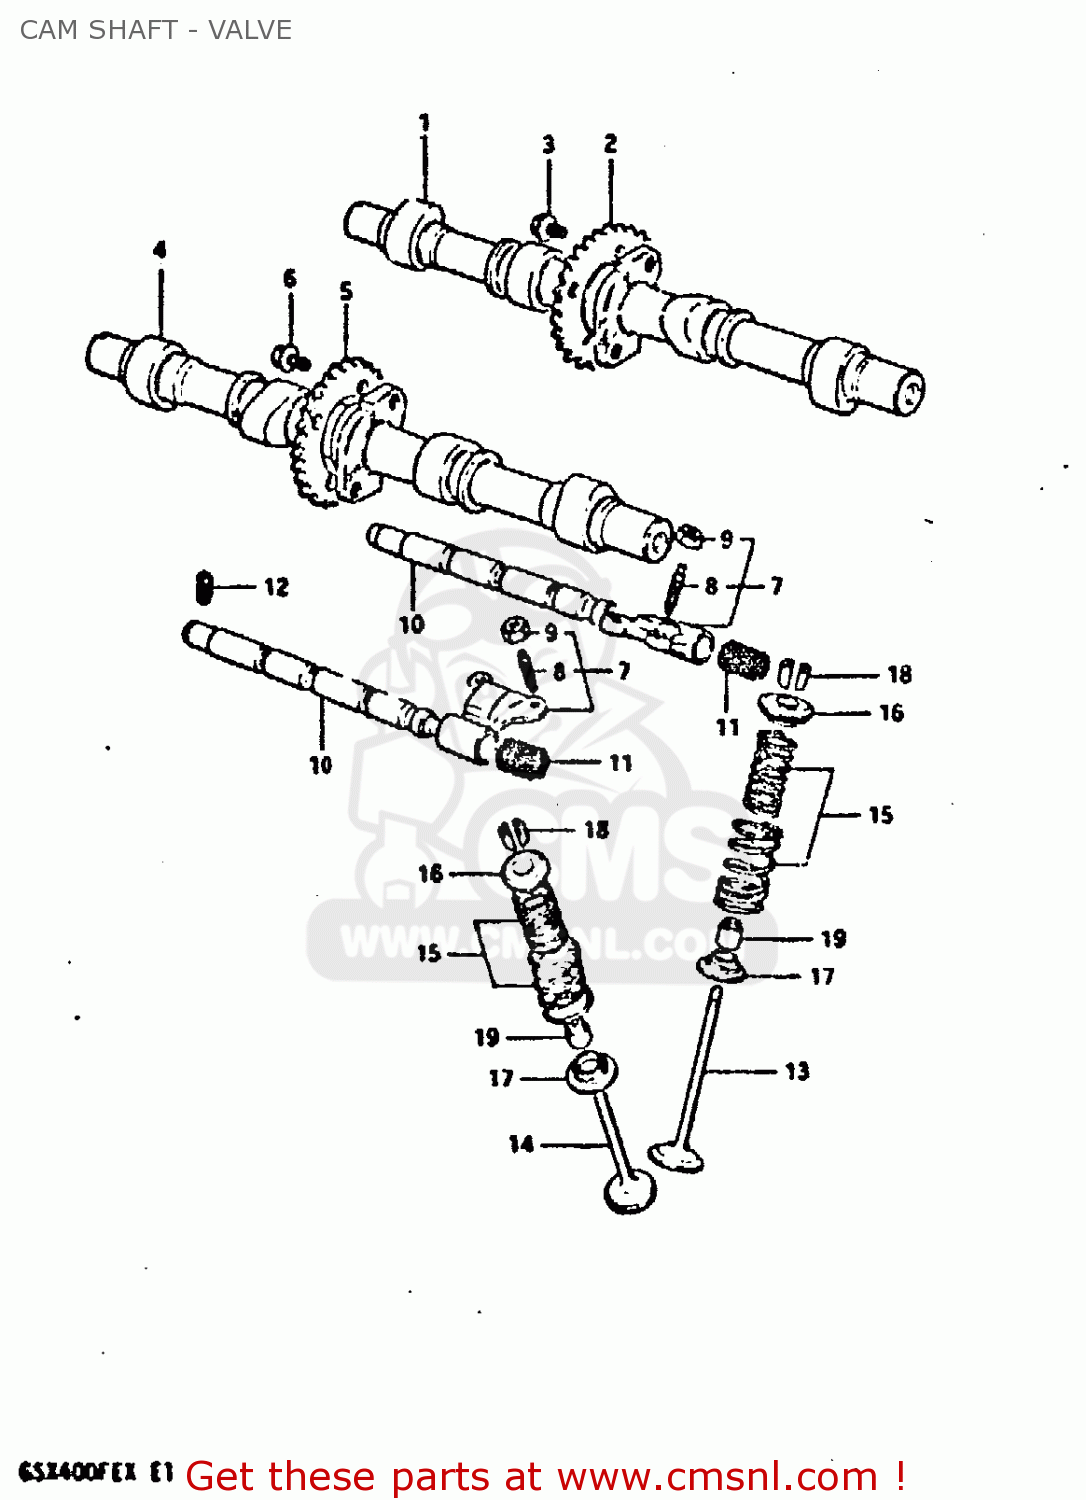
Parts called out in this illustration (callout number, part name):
1	CAM SHAFT, INTAKE
2	SPROCKET, EXHAUST CAM SHAFT
3	BOLT(7X11)
4	CAM SHAFT, EXHAUST
5	SPROCKET, EXHAUST CAM SHAFT
6	BOLT(7X11)
7	ARM, VALVE ROCKER INTAKE
8	SCREW,TAPPET ADJUSTING
9	NUT,ADJUSTING
10	SHAFT, VALVE ROCKER ARM
11	SPRING
12	SCREW
13	VALVE,INTAKE
14	VALVE, EXHAUST
15	SPRING SET, VALVE
16	RETAINER,VALVE SPRING
17	SEAT,VALVE SPRING
18	COTTER VALVE
19	OIL SEAL
